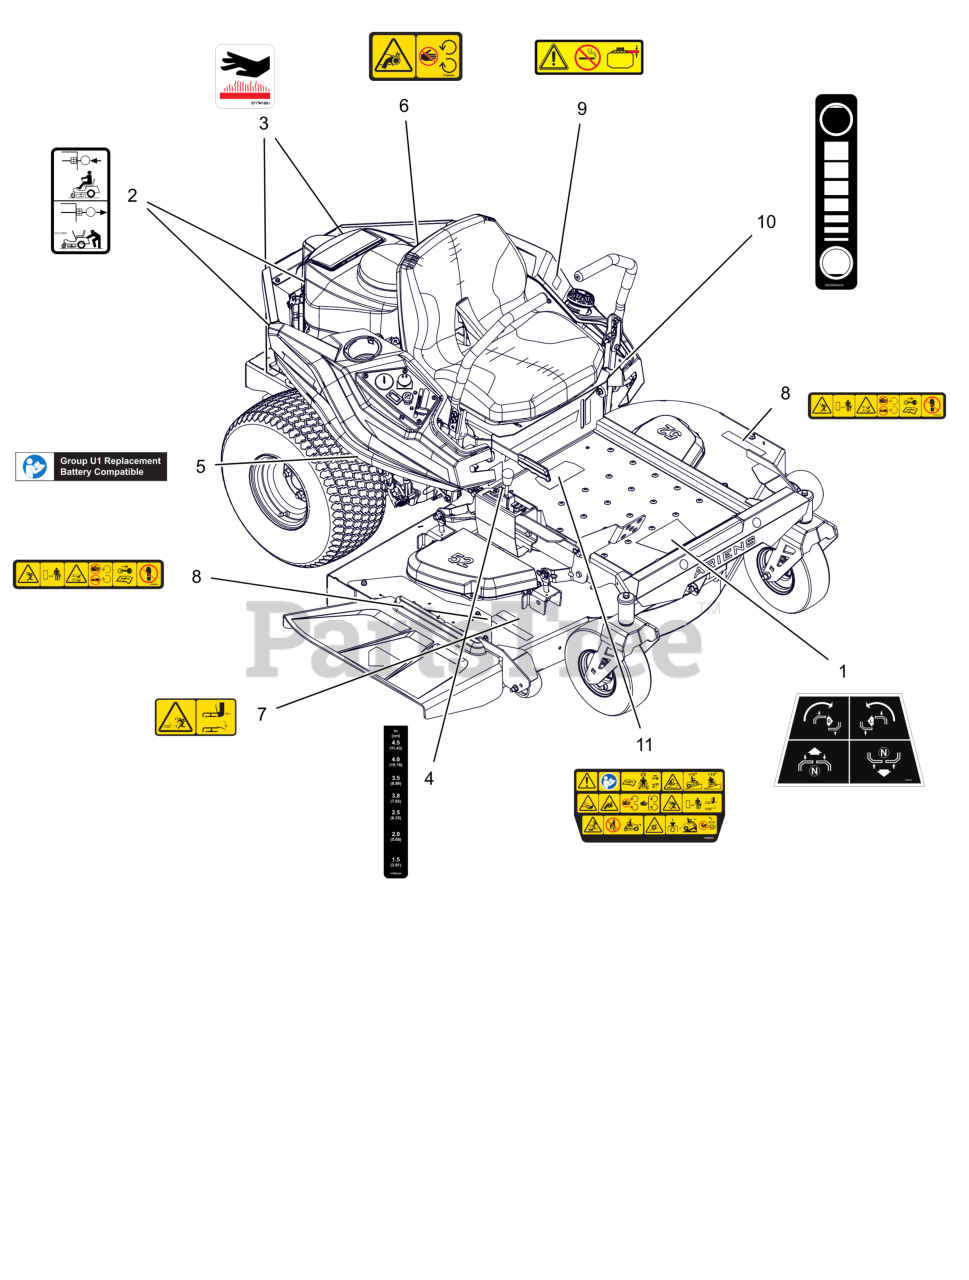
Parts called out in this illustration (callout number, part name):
1	DECAL, STEERING
2	DECAL, TRANSMISSION DISCONNECT
3	DECAL, HOT SURFACE
4	DECAL, HEIGHT OF CUT
5	DECAL, U1 BATTERY REPLACEMENT
6	DECAL, SAFETY - GUARDING
7	DECAL, SAFETY - DECK GUARDING
8	DECAL, DECK SAFETY
9	DECAL, FUEL WARNING
10	DECAL, FUEL LEVEL
11	DECAL, MAIN SAFETY
